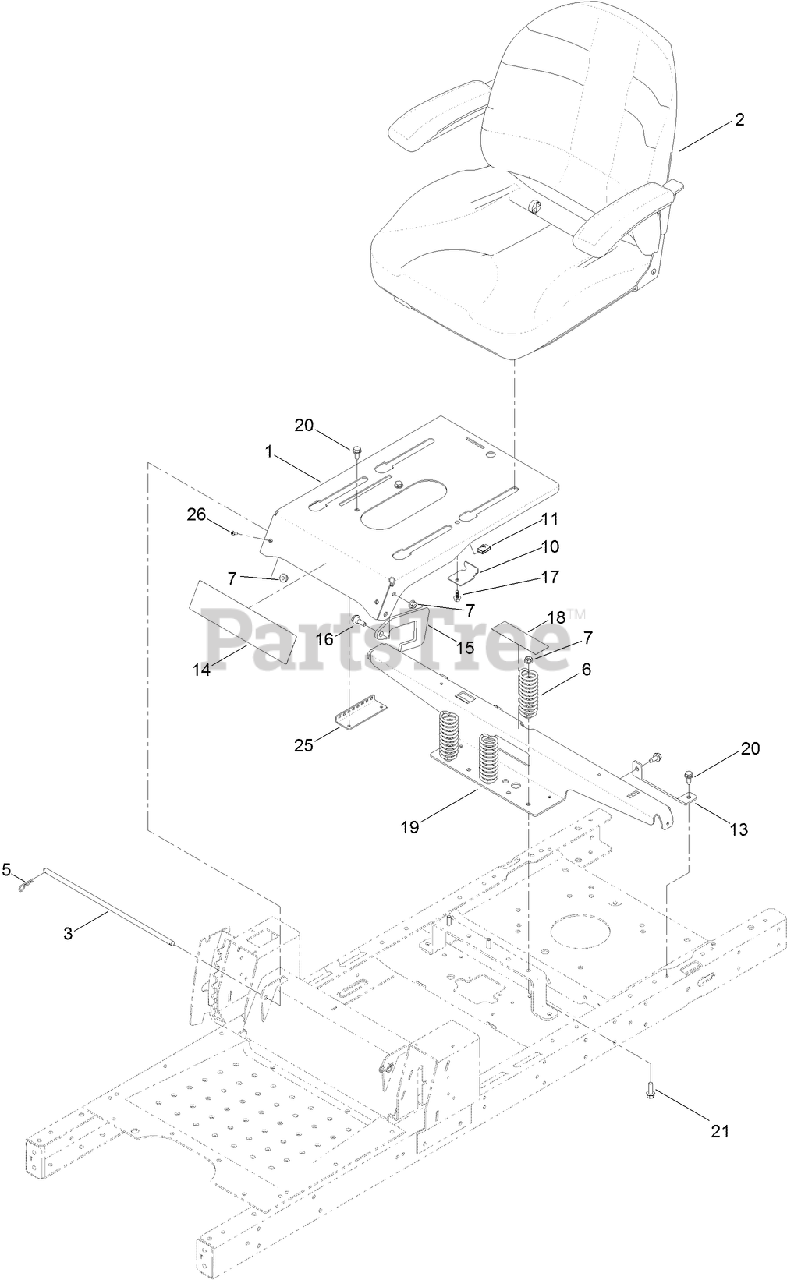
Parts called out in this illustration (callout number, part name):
2	SEAT ASM
3	ROD-PIVOT, NARROW
5	PIN-COTTER
6	SPRING-COMPRESSION
7	NUT-HF, NI
10	BRACKET-STOP, SEAT
13	SUPPORT-TANK, REAR
14	DECAL-TIMECUTTER
15	PLATE-STOP
16	SCREW-SHOULDER
17	SCREW-HHF
18	DECAL-SERVICE, CE
19	SUPPORT-POD
20	SCREW-HWHTF
21	SCREW-HHF
25	BRACKET-LATCH, SEAT
26	SCREW-HSBH
